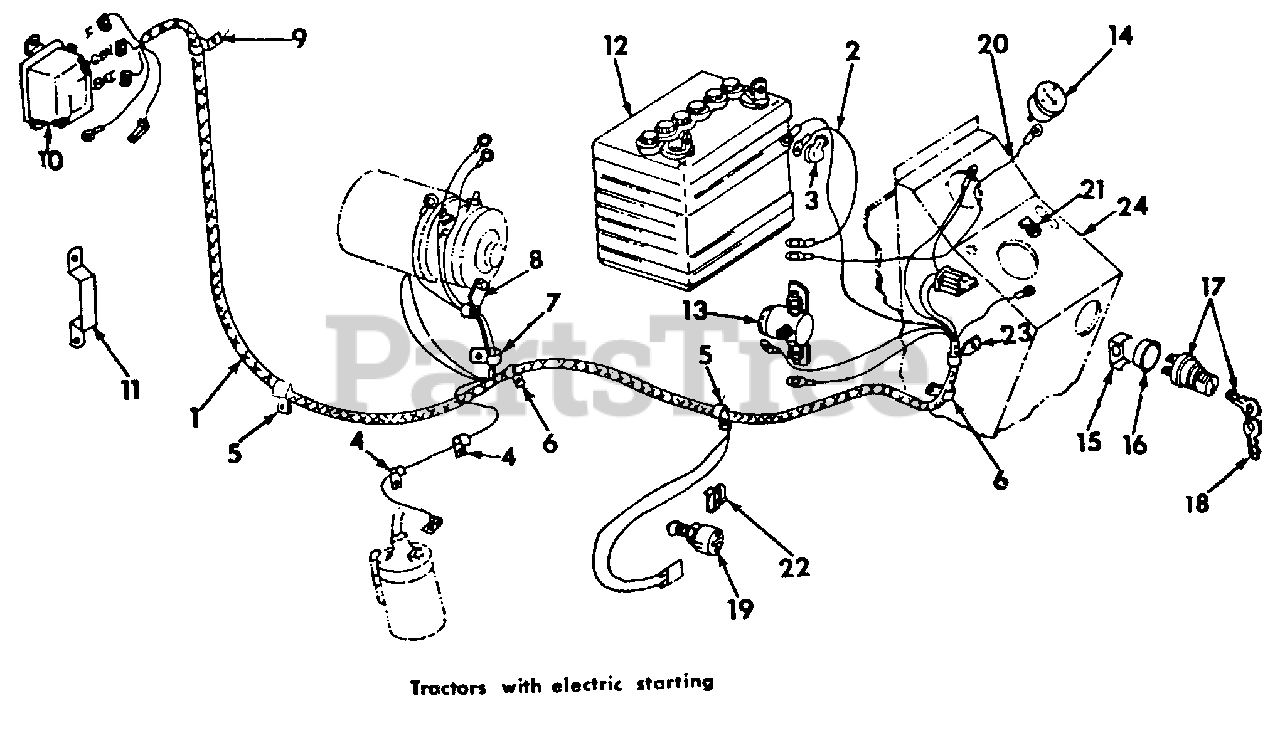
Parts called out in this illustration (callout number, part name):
1	Harness Assy, Cable
2	Cable Assy, Battery to Magnetic Switch
3	Cover, Battery Terminal
4	Clip, Ignition Cable
5	Clip, Cable Harness
6	Clip, Cable Harness, Long
7	Clip, Generator Cable
8	Clip, Cable Harness
9	Clip, Cable Harness
10	Regulator, Voltage
11	Bracket, Voltage Regulator
12	Battery, Prestolite 9948X, 12 Volt
13	Switch Assy, Magnetic
14	Indicator Assy, Charge
15	Retainer, Ignition Switch
16	Socket, Ignition Switch
17	Switch Assy, Battery Ignition Switch
18	Key, Switch
19	Switch Assy, Safety Starting
20	Cable Assy, Charge Indicator
21	Not used in this application
22	Clip, Safety Starting Switch Cable Snap On
23	Clip, Cable Harness
24	Pedestal Assy
